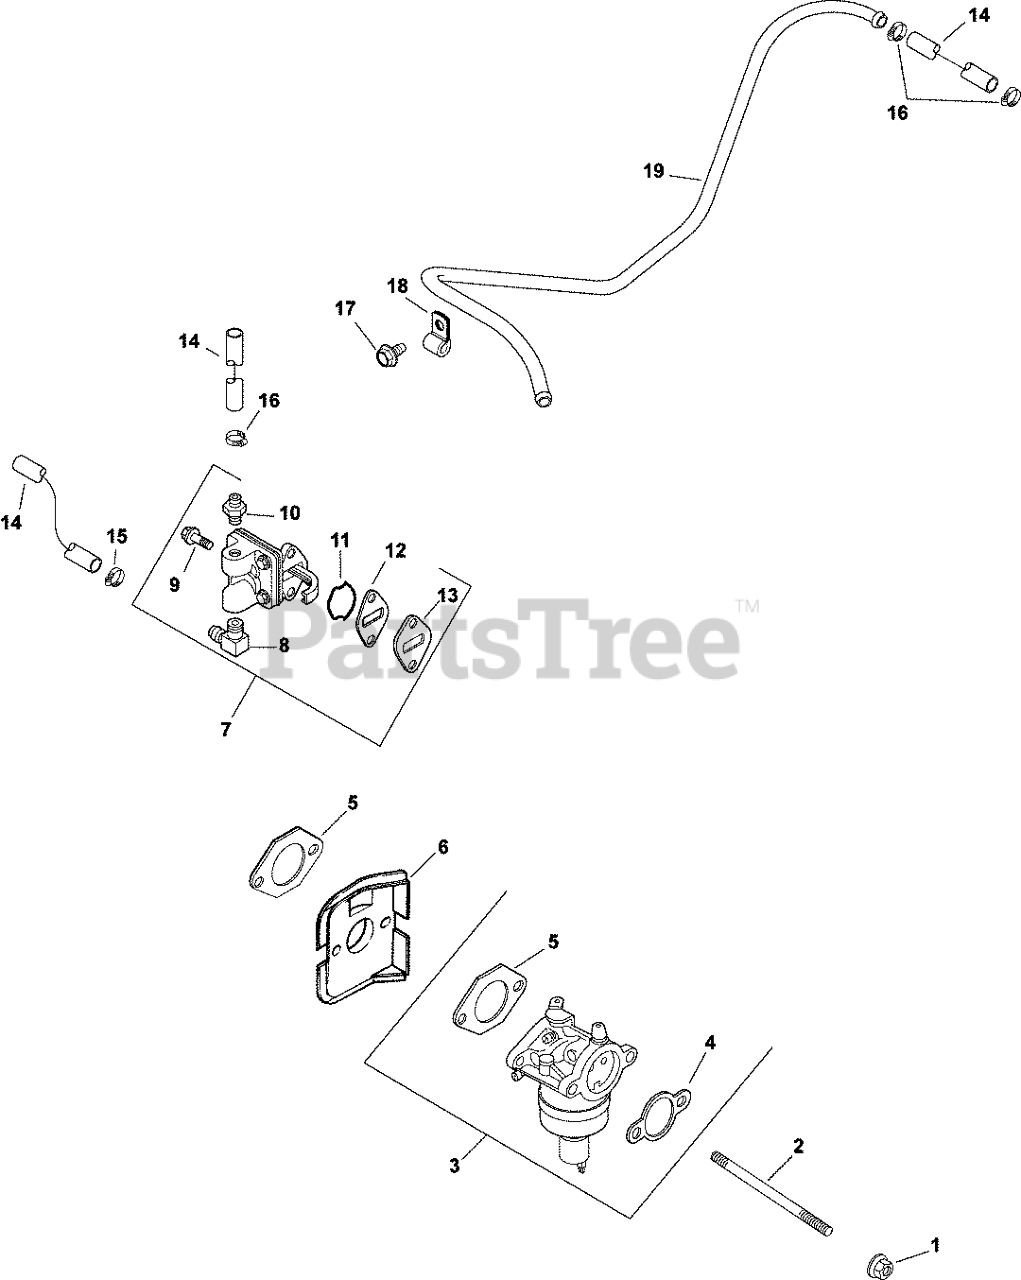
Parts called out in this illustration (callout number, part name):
1	NUT, FLG M6X1.0
2	STUD,M6X1.0X116
3	KIT, CARBURETOR w/GASKETS
4	GASKET, AIR CLEANER BASE
5	GASKET, CARBURETOR
6	DEFLECTOR, HEAT
7	KIT, FUEL PUMP
8	CONNECTOR, 90 DEG. HOSE
9	SCREW, LBD SKT M6x1.0x20-(#25086403S)
10	KIT, STRAIGHT FITTING
11	O-RING, FUEL PUMP
12	GASKET, FUEL PUMP
13	SPACER, FUEL PUMP
14	HOSE,LW PERM.FUEL 24.00"-USE 25 111 81-S
15	CLAMP, BAND SPRING HOSE-(#2523737S)
16	CLAMP, HOSE (KM)-USE 25 237 31-S
17	SCREW, FLG THD FRM M5X.8X10
18	CLIP, TUBE & WIRING (KM)
19	LINE, FUEL
1285380-S	CARBURETOR W/GASEKTS - USE 12 853 139-S
